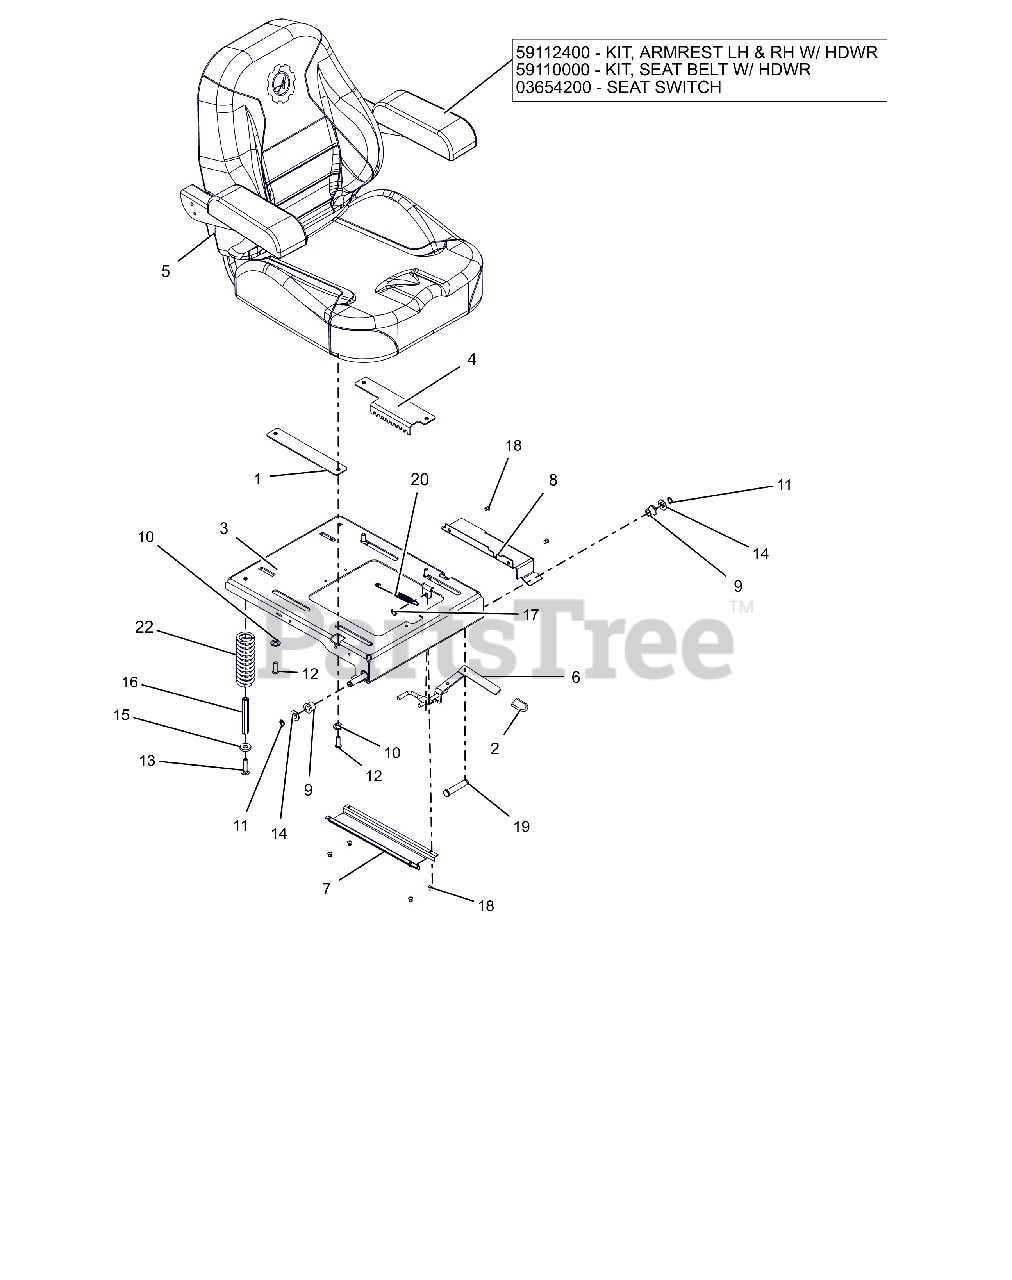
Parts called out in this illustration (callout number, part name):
1	PLATE, ADJUSTABLE SEAT SLIDE
2	GRIP, SEAT LEVER, GREY
3	WLDMT, SEAT PLATE HD
4	PLATE, HD SEAT ADJUSTMENT
5	SEAT, APEX
5	KIT-LH & RH ARM REST-05124700
5	KIT-SEAT BELT REPLACE-05007300
5	SWITCH- SEAT
6	WLDMT, SEAT SLIDE LEVER
7	GUARD,SEAT SWITCH
8	GUARD, SEAT PLATE CE
9	BSHG, FLG .516X.750X.625X.937
10	BSHG-FLG .32X.500X.344X.880
11	RG-RTNG-EXT .500X.050 (SNAP)
12	SCR-SKH .31-18X1.0 BTNHD YWZC
13	@BLT-RDHDSQNK .31-18X1.50 G5YZ
14	WSHR-FL-STL.531X1.00X.063 YWZC
15	WSHR-FL-STL .406X1.00X.188 YWZ
16	NUT, COUPLING 5/16X18 X 3.75
17	NUT-PUSH .312
18	RIVET, .1875 AL/AL .126-.250
19	PIN, SEAT PIVOT -.500X2.31
20	SG-TENS .06X.482X5.35
22	SPRING, COMPRESSION SEAT 224LB
